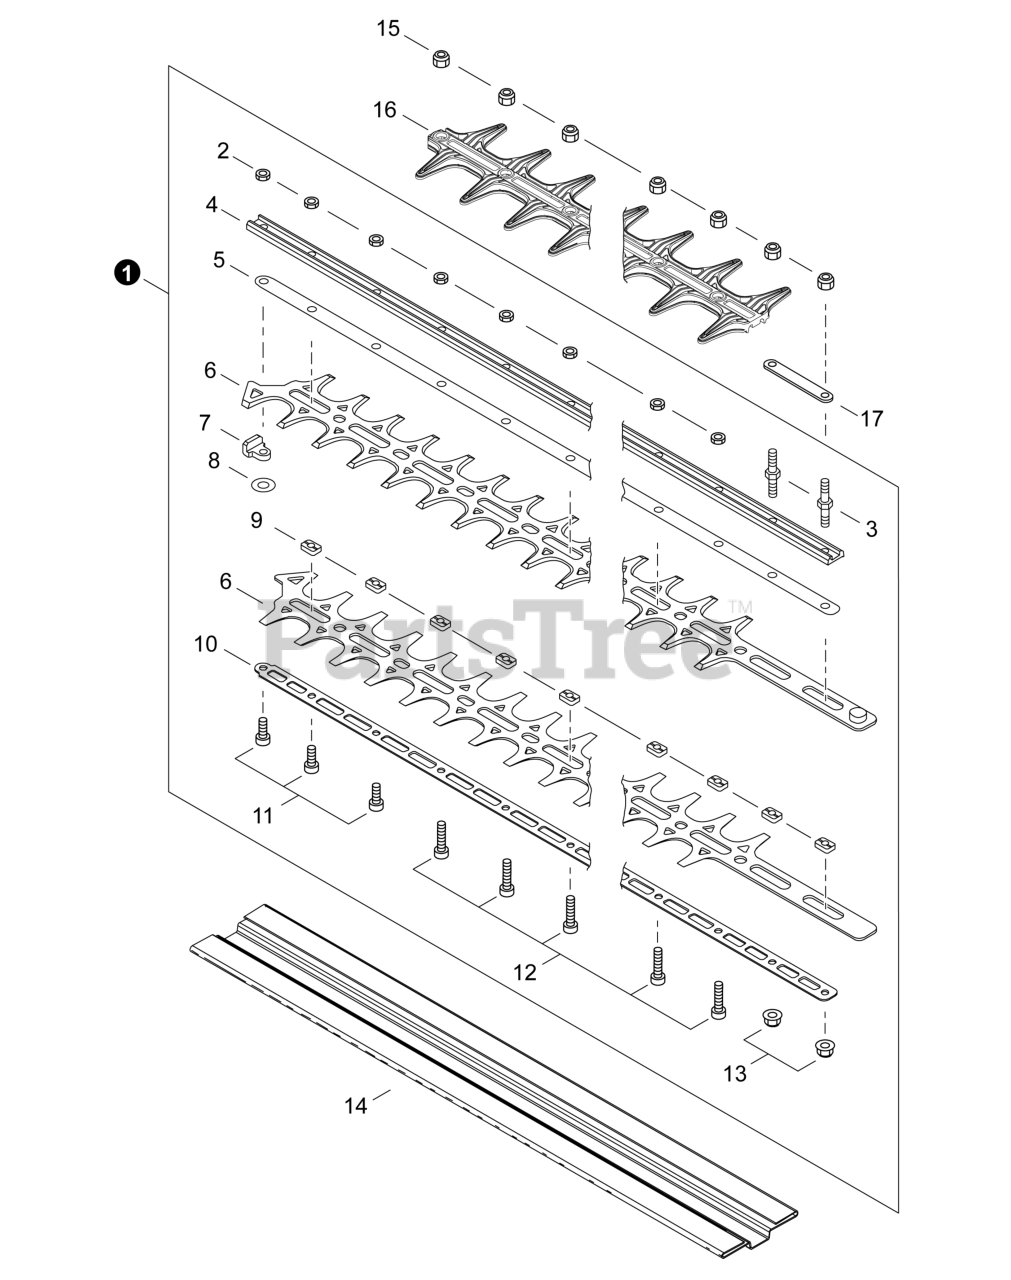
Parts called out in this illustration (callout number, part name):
1	CUTTER ASSY, 30"
3	STUD, MOUNTING M5x36
4	SUPPORT, BLADE 28"
5	SUPPORT, BLADE 28"
6	CUTTER 30"
10	SUPPORT, BLADE 30"
11	BOLT, TORX 5x16
12	BOLT, TORX 5x25
13	NUT, FLANGE M5
14	SCABBARD
15	NUT, FLANGE M5
16	GUARD, CUTTER BLADE
17	PLATE, EYE
